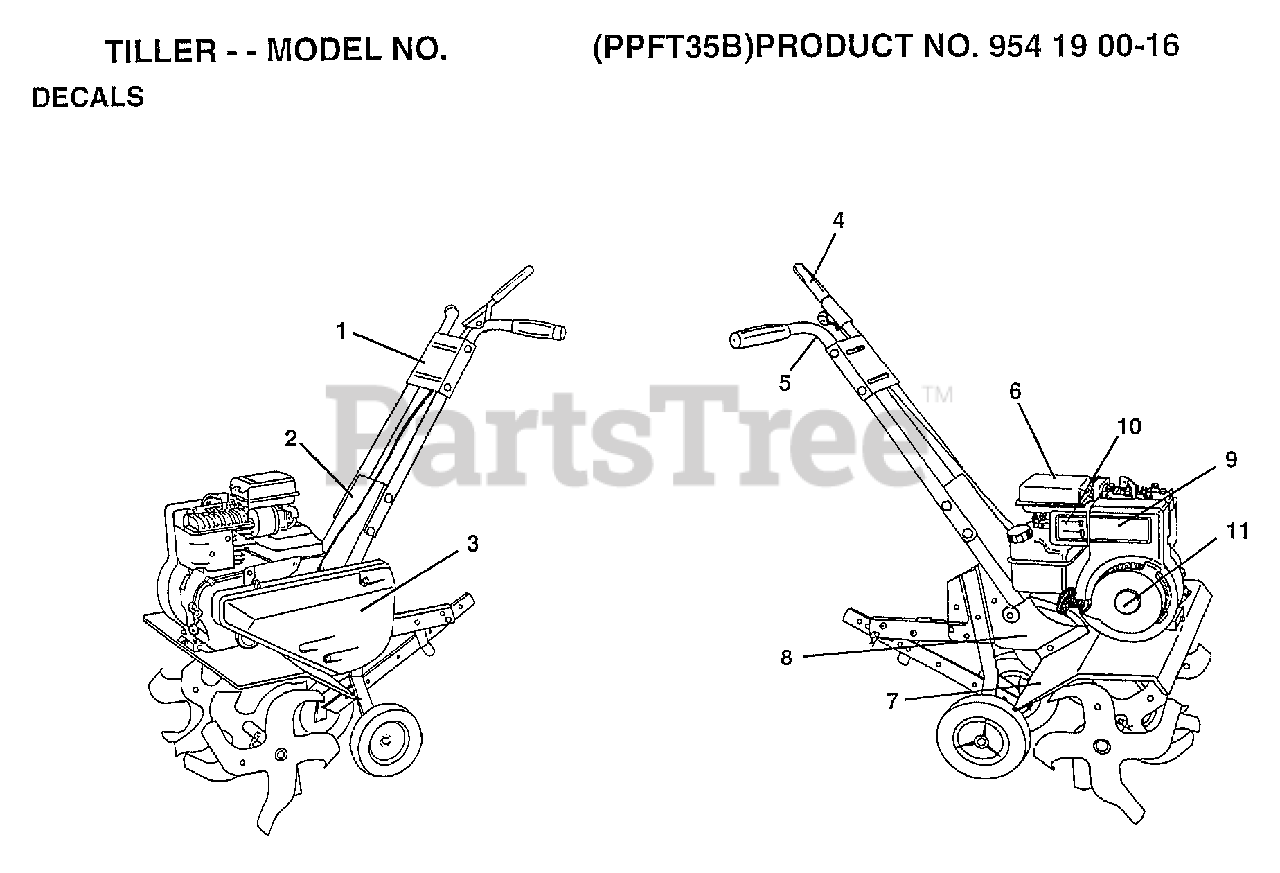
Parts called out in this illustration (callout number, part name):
1	DECAL.LOGO.CONTROL
2	DECAL.HP.CONTROL
4	DECAL, TINE CONTROL
5	DECAL HAND PLACEMENT
6	DECAL.CAUTION
7	DECAL WARNING ROTATING TINES
8	RETAINER-SPRING
9	DECAL-BRIGGS AND STRATTON
10	DECAL-SPEED CONTROL
11	DECAL-3.5 HP
